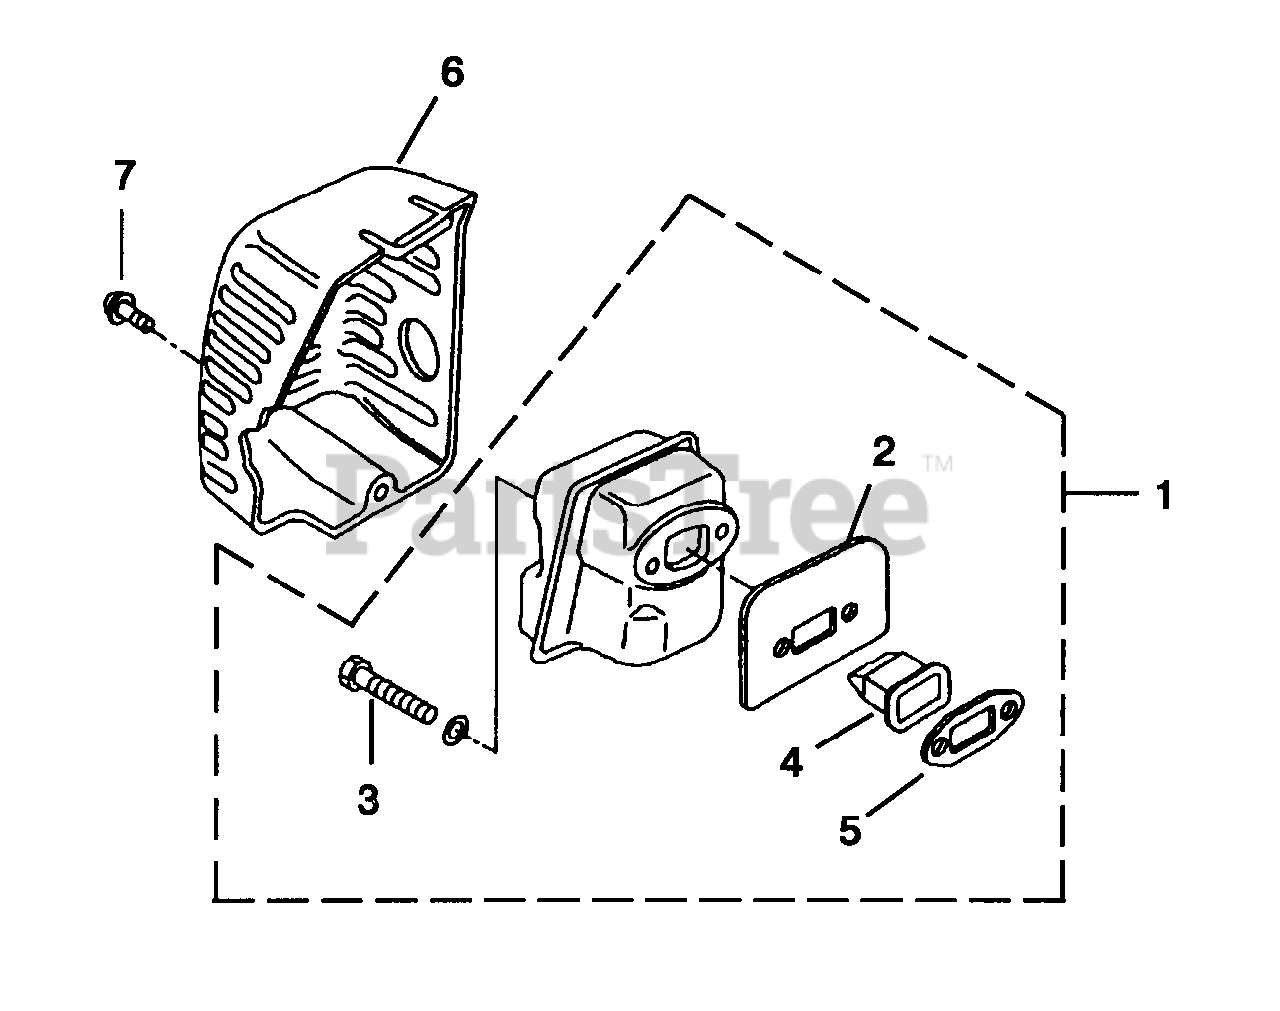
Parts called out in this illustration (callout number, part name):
1	MUFFLER KIT
2	GASKET-Muffler
3	SCREW-Socket Hd (MS x 50)
4	SPARK ARRESTOR SCREEN
5	GASKET-Muffler
6	MUFFLER COVER
7	SCREW ASSEMBLY (M5 x 16)
